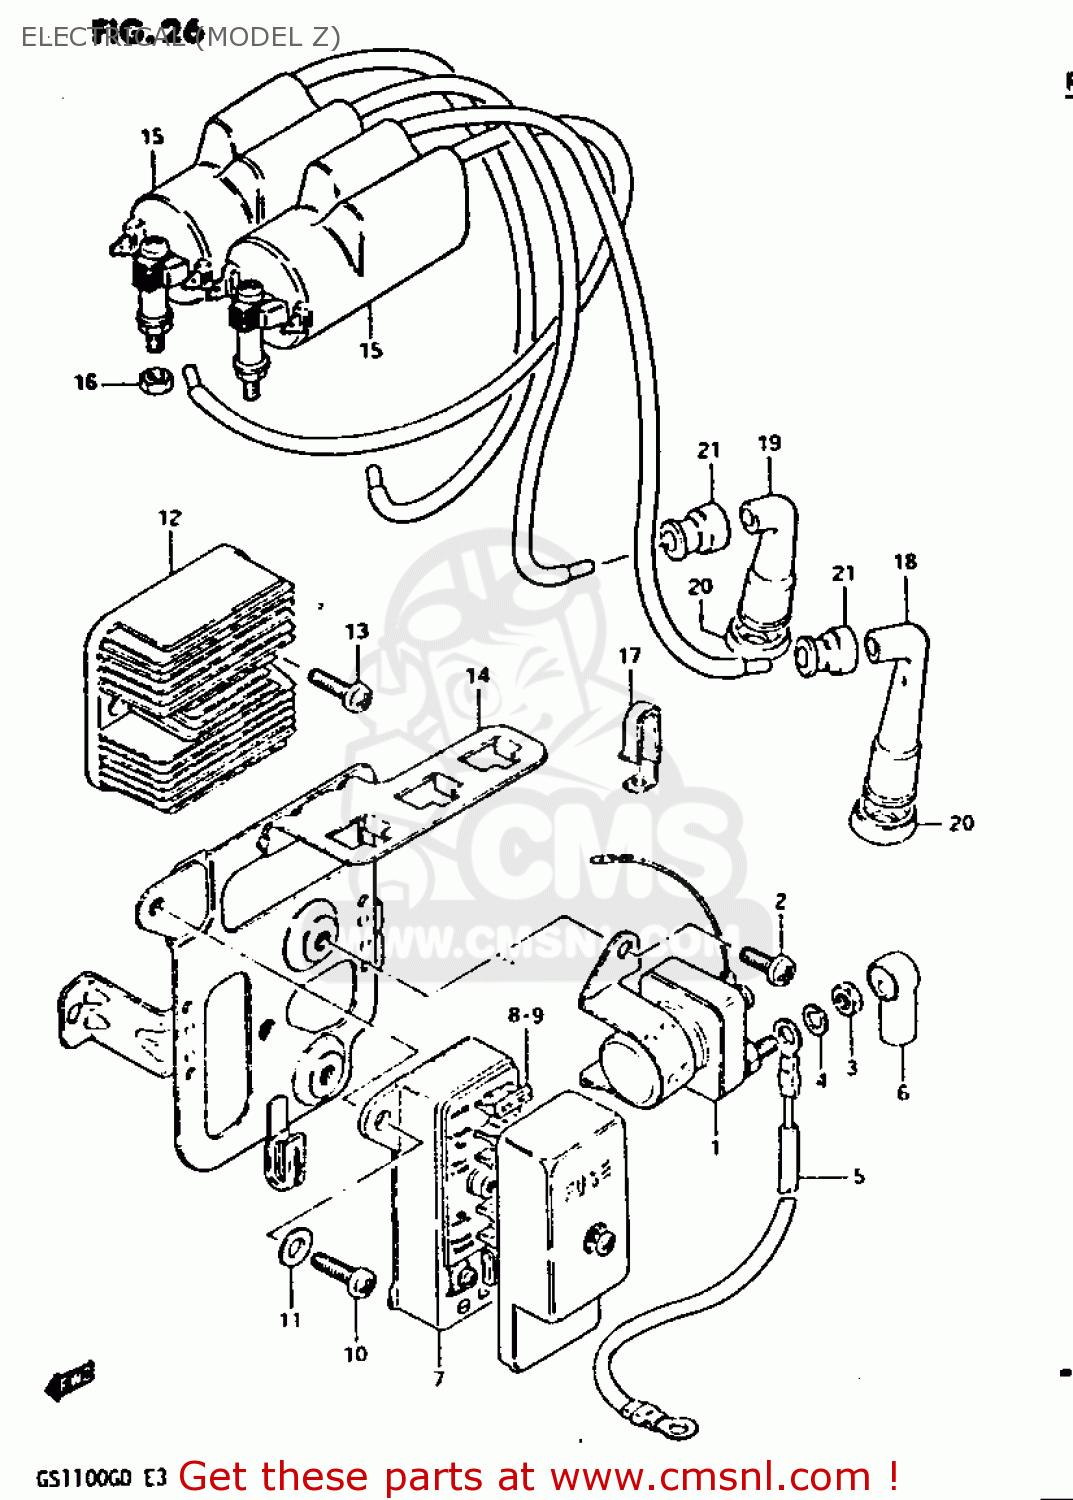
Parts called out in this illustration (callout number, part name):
1	RELAY ASSY,STARTING MOTOR
2	SCREW
3	NUT 6MM
4	WASHER,LOCK
5	CABLE,STARTING MOTOR
6	CAP,TERMINAL
7	BOX ASSEMBLY,FUSE
8	FUSE(10A)
9	FUSE(15A)
10	SCREW 6X12
11	WASHER
12	RECTIFIER ASSEMBLY
13	SCREW 6X12
14	HOLDER COMP,ELECTRONIC PARTS
15	COIL ASSEMBLY,IGNITION
16	NUT
17	CLAMP
18	CAP ASSY,SPARK PLUG
19	CAP,SPARK PLUG
20	SEAL,SPARK PLUG
21	SEAL,SPARK PLU
